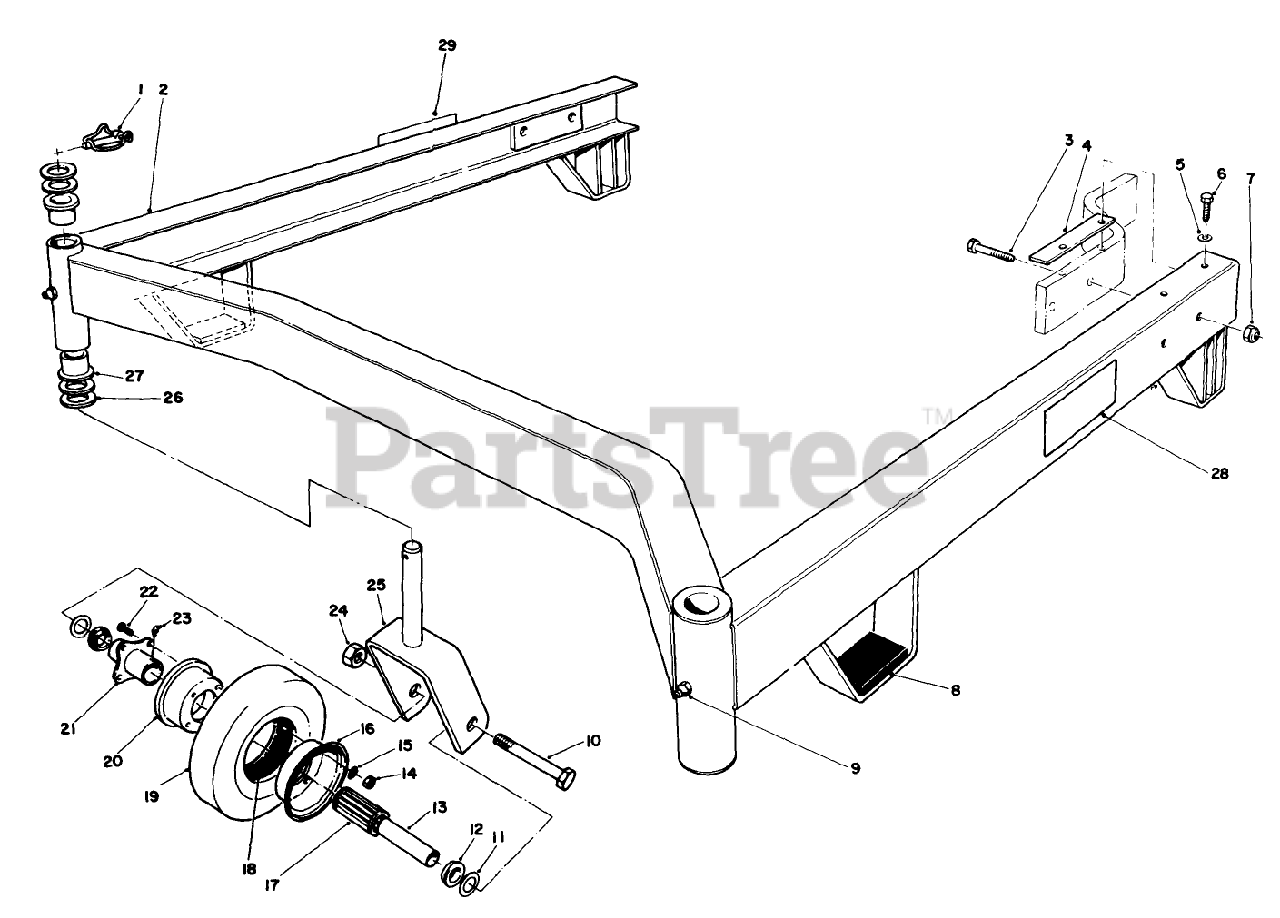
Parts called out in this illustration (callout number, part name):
1	PIN-LYNCH
2	52" Suspension Assembly (Incl. Ref. #9, 26 & 27)
3	SCREW-HH
4	SHIM-CARRIER
5	WASHER-FLAT
6	SCREW-HHF
7	NUT-LOCK, CONE
8	CUSHION-RUBBER
9	FITTING-GREASE
10	SCREW-HH
11	WASHER-FLAT
12	Bushing
13	SPANNER-TIRE
14	NUT-HEX
15	WASHER-LOCK
16	MALE WHEEL HALF
17	BEARING-ROLLER
18	TUBE-INNER (W/VALVE)
20	FEMALE WHEEL HALF
21	HUB-CENTER
22	WHEEL BOLT
23	FITTING-GREASE
24	NUT-HEX
25	Castor Fork
26	WASHER-THRUST
27	Bushing
28	DECAL-FUEL SHUT OFF
29	DECAL-HOC, LH
